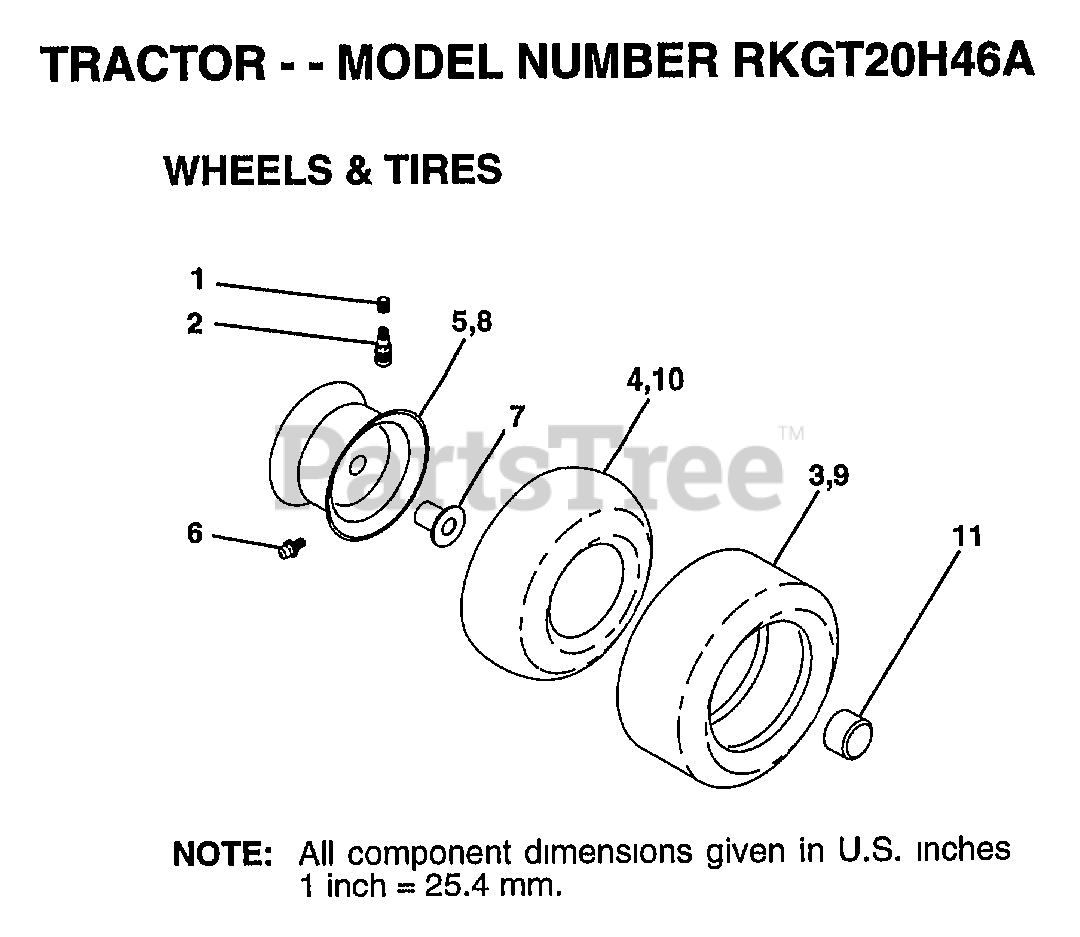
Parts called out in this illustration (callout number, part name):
1	VALVE CAP
2	VALVE STEM LT
4	TUBE.5.3/4.5/6
5	"RIM ASM 6"" FRT"
6	FITTING LT
7	"FLANGE, BEARING"
8	RIM.REAR.
10	TUBE.23X8/10-12
11	HUB CAP
